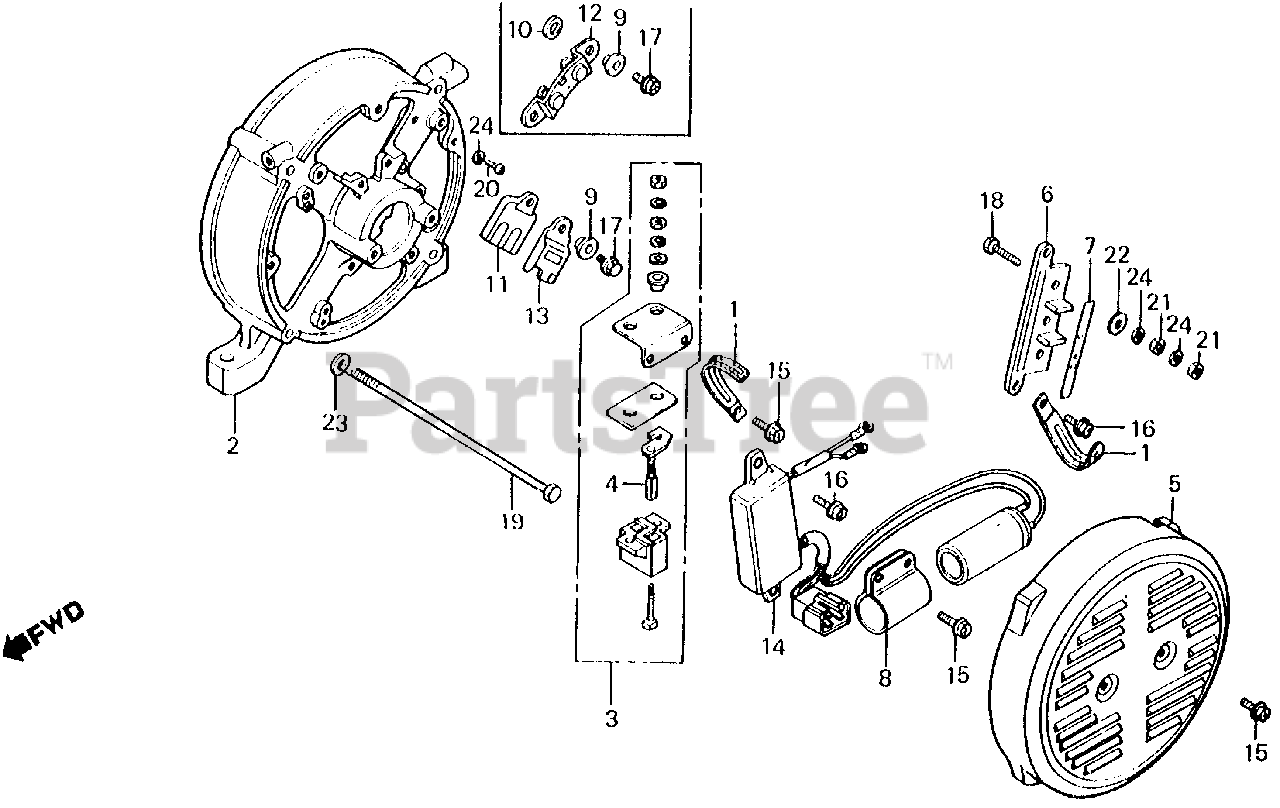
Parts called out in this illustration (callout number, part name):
1	CLAMP A, WIRE
2	HOUSING, RR. *R8* (BRIGHT RED) (NOT AVAILABLE)
3	HOLDER, BRUSH
5	COVER, ALTERNATOR END *R8* (BRIGHT RED)
6	TERMINAL, VOLT CHANGE
7	MARK, VOLT
8	HOLDER, CONDENSER
9	BUSH, INSULATING
10	WASHER, INSULATING
11	INSULATOR, DIODE
12	DIODE ASSY., D.C.
13	DIODE, D.C.
14	REGULATOR ASSY., AUTOMATIC VOLTAGE
15	SCREW, TAPPING (5X12)
16	SCREW, TAPPING (5X14)
17	SCREW, TAPPING (5X16)
18	BOLT, HEX. (5X20)
19	BOLT, HEX. (6X130) (NOT AVAILABLE)
20	SCREW, PAN (5X12)
21	NUT, HEX. (5MM)
22	WASHER, PLAIN (5MM)
23	WASHER, PLAIN (6MM)
24	WASHER, SPRING (5MM)
